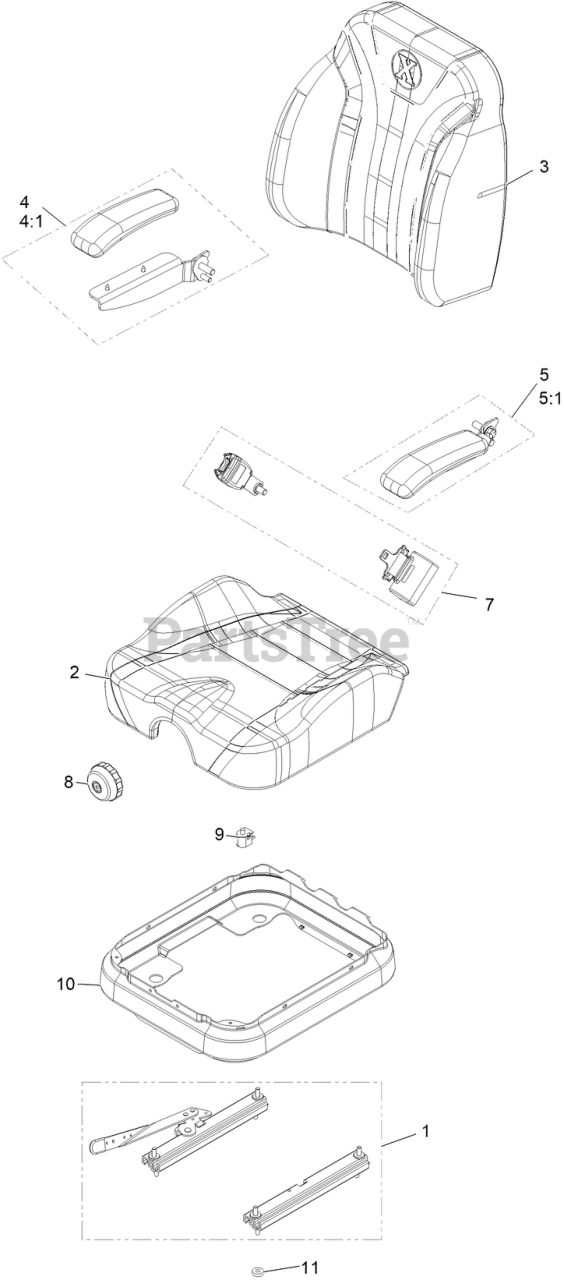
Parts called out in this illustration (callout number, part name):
1	TRACKS-4" TRAVEL
2	COVER, LOWER
3	COVER, UPPER
4	RH Arm Rest Kit
4:1	CUSHION-REST, ARM
5	LH Arm Rest Kit
5:1	CUSHION-REST, ARM
7	KIT-SEAT BELT
8	KNOB-ADJUSTER
9	SWITCH-BAIL
10	BELLOWS-SEAT
